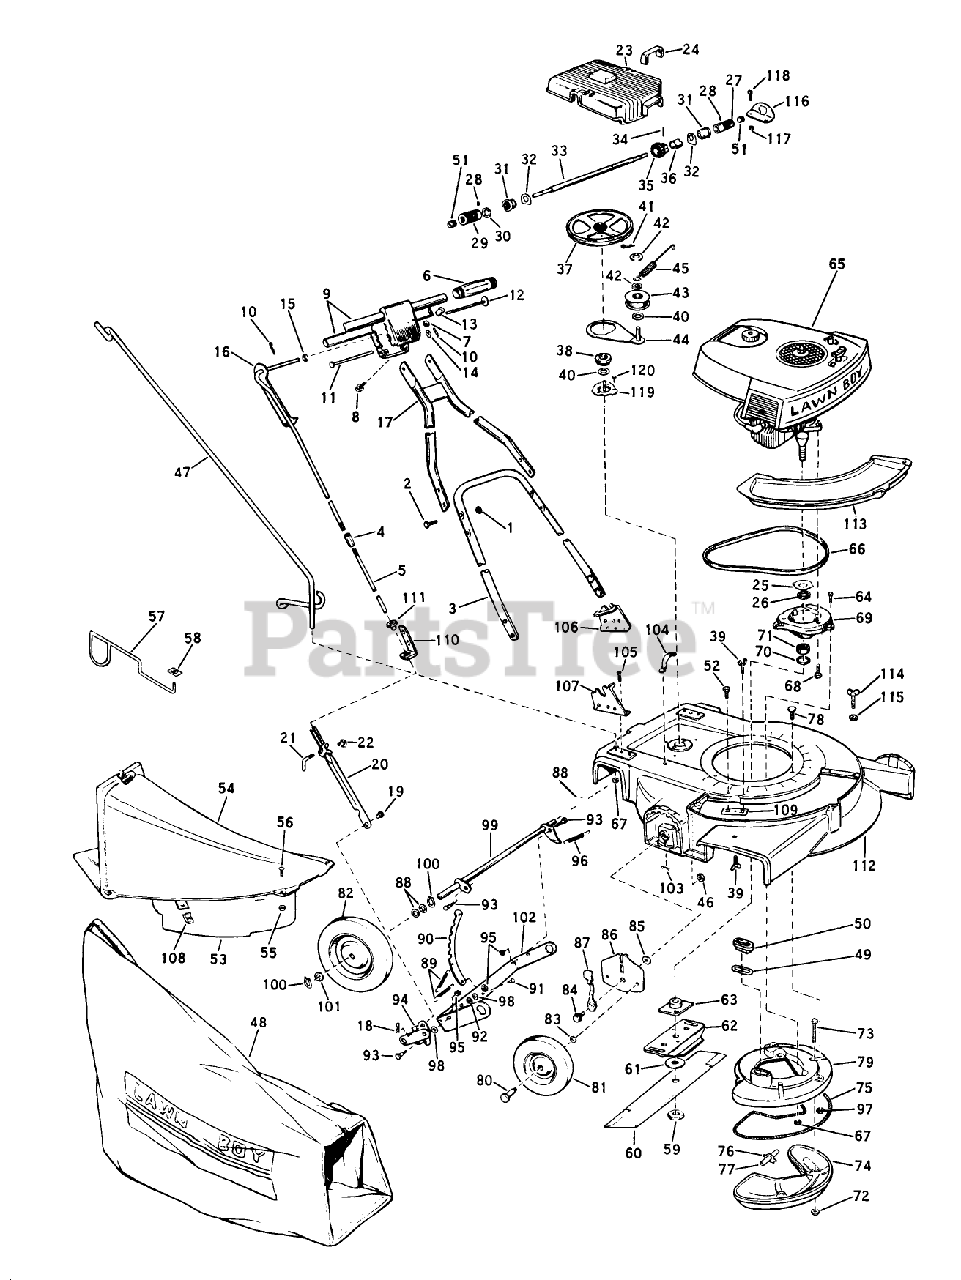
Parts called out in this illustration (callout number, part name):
1	STOP NUT
10	Pin-Cotter
37	PULLEY&OILER FELT (13)
48	89802 LB WHOLE GOODS
49	GASKET S
51	GREASE PLUG
53	Skirt Assembly-Chute (Includes Hardware)
54	Chute and Spring Assy. (Includes Hardware)
59	NUT-BLADE
63	PLATE AND COLLAR ASM
72	LOCKNUT E
76	Gasket-Internal Tube
77	Tube-Internal Muffler
80	BOLT WHEEL
83	WASHER WROUGHT
93	BOLT RB&W
95	STOP NUT
98	WASHER S
100	RETAINING RING
105	SCREW S
108	SPEED NUT ARDEN
117	STOP NUT
